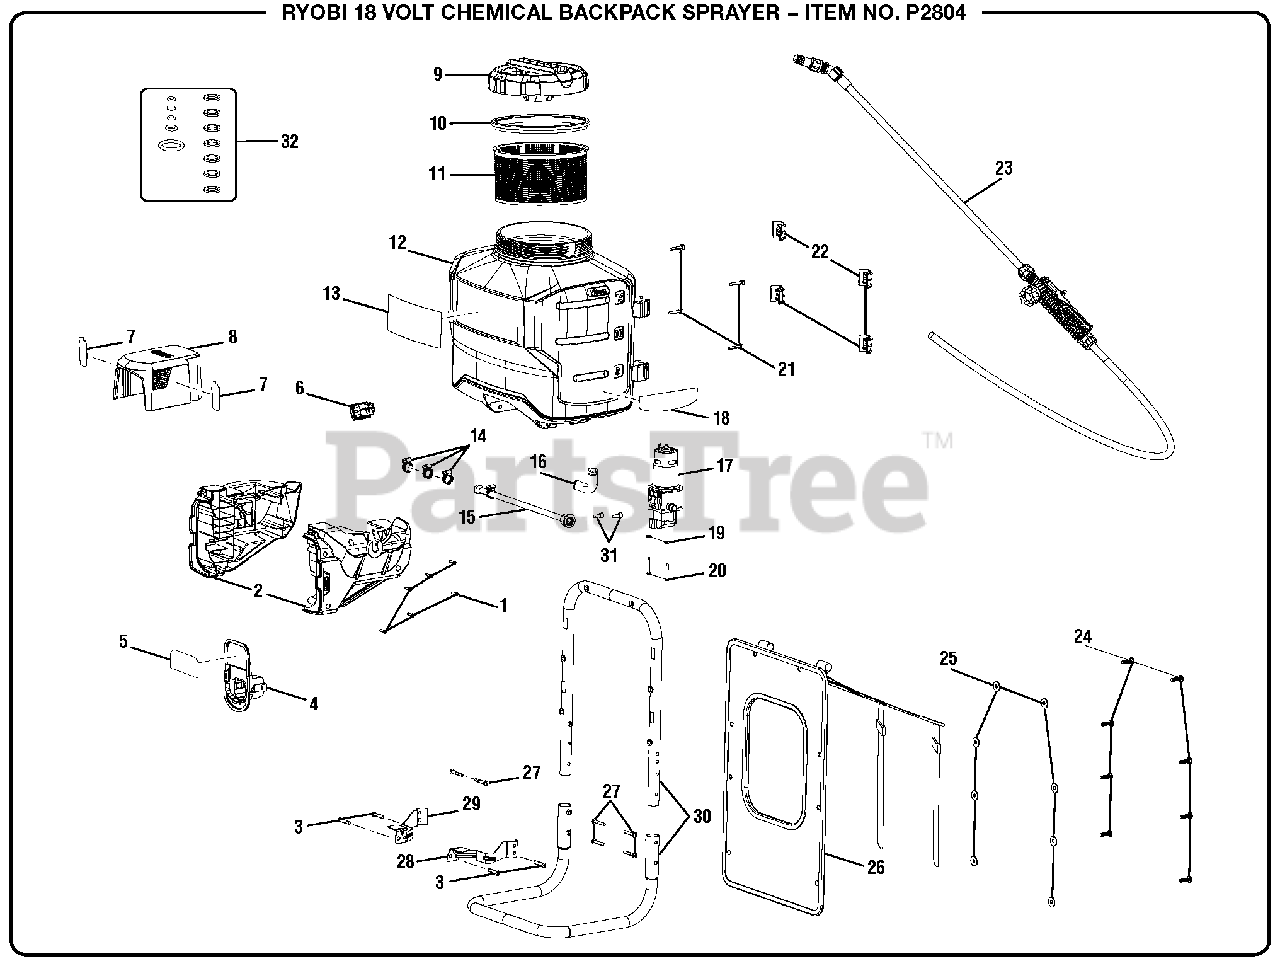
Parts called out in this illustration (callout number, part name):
1	Screw (M4 x 14 mm, T15 Torx Pan Hd.)
2	Sprayer Housing Assembly
3	Screw (M5 x 25 mm, T25 Torx Pan Hd.)
4	Battery Foot
5	Data Label
7	Lithium Label
8	Battery Cover Assembly
9	Tank Lid Assembly
10	Rubber Gasket
11	Filter and Seal Assembly
12	Tank Assembly
13	Front Logo Label
14	Hose Clamp
15	Filter and Tube Assembly
16	Elbow Tube (OD16 x ID10)
17	Motor and Pump Assembly
18	Warning Icon Label
19	Washer (ID4.2 x OD10 x 1t)
20	Screw (M4 x 30 mm, T15 Torx Pan Hd.)
21	Screw w/Washer (M5 x 25.4 mm, T25 Pan Hd. T.F.)
22	Tank Holder
23	Trigger Handle Assembly
24	Screw (M6 x 20 mm, Pan Hd.)
25	Washer (ID6.8 x OD16 x 1.5t)
26	Backpack Harness
27	Screw (M5 x 30, T20 Torx Pan Hd.)
28	Bottom Right Bracket
29	Bottom Left Bracket
30	Frame Assembly
31	Wire Connector
32	Seals For Life O-Ring Kit (See Page 4)
